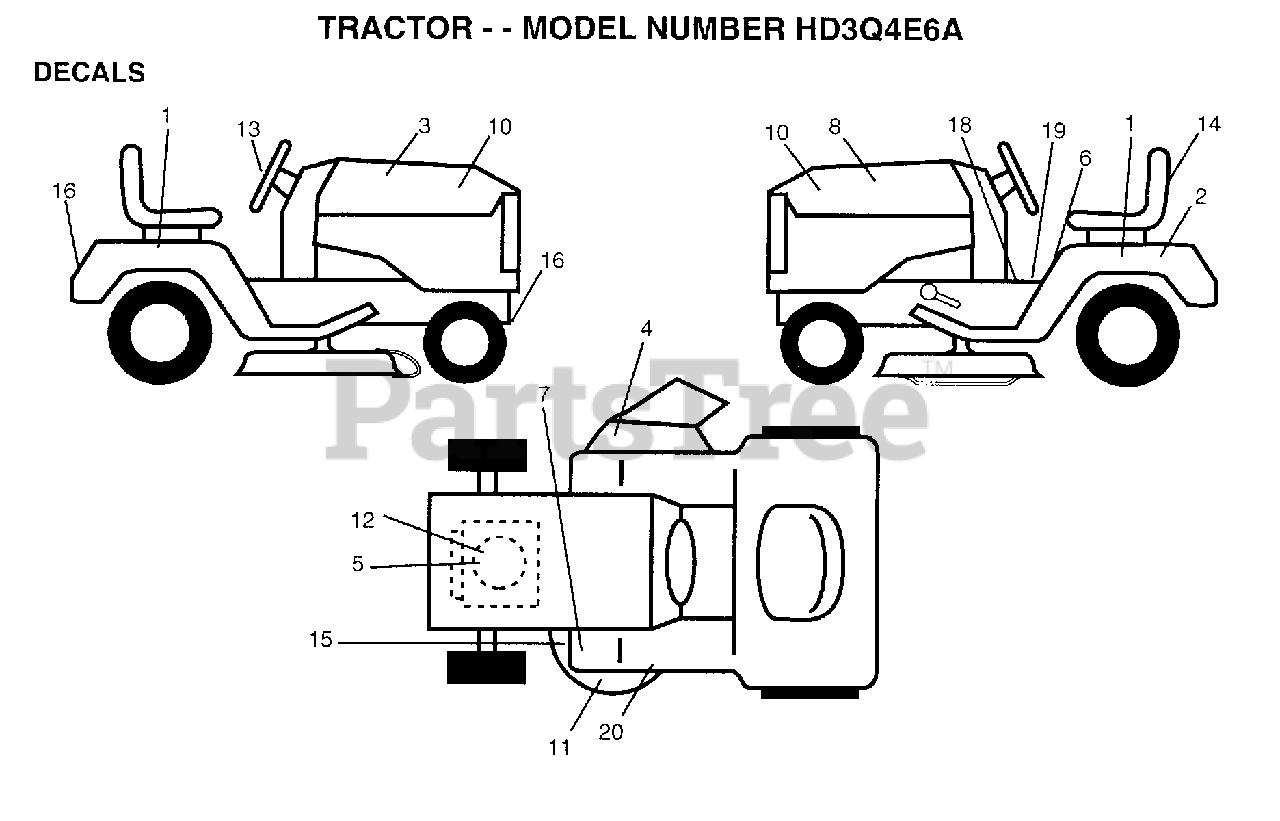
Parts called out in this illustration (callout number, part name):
1	DECAL.FENDER.AUTO
2	DECAL.BTRY.DANGER
3	DECAL HOOD RH
4	"DECAL, WARNING"
5	DECAL, HP, ENGINE
6	DECAL CAUT FEND
7	DECAL CLUT/BRAKE
8	DECAL HOOD LH
9	HARNESS.ENG.B&S
10	DECAL.PNL.SD.HDPO
11	DECAL.DECK.MULCH.
12	DECAL.PART.18.5HP
13	DECAL.INST.WHL.ST
15	DECAL.SCH.PRIM.42
16	DECAL.FENDER.HDEP
18	DECAL.CLD.START.H
19	DECAL.SADDLE.INST
20	DECAL.SCH.PRIM.42
